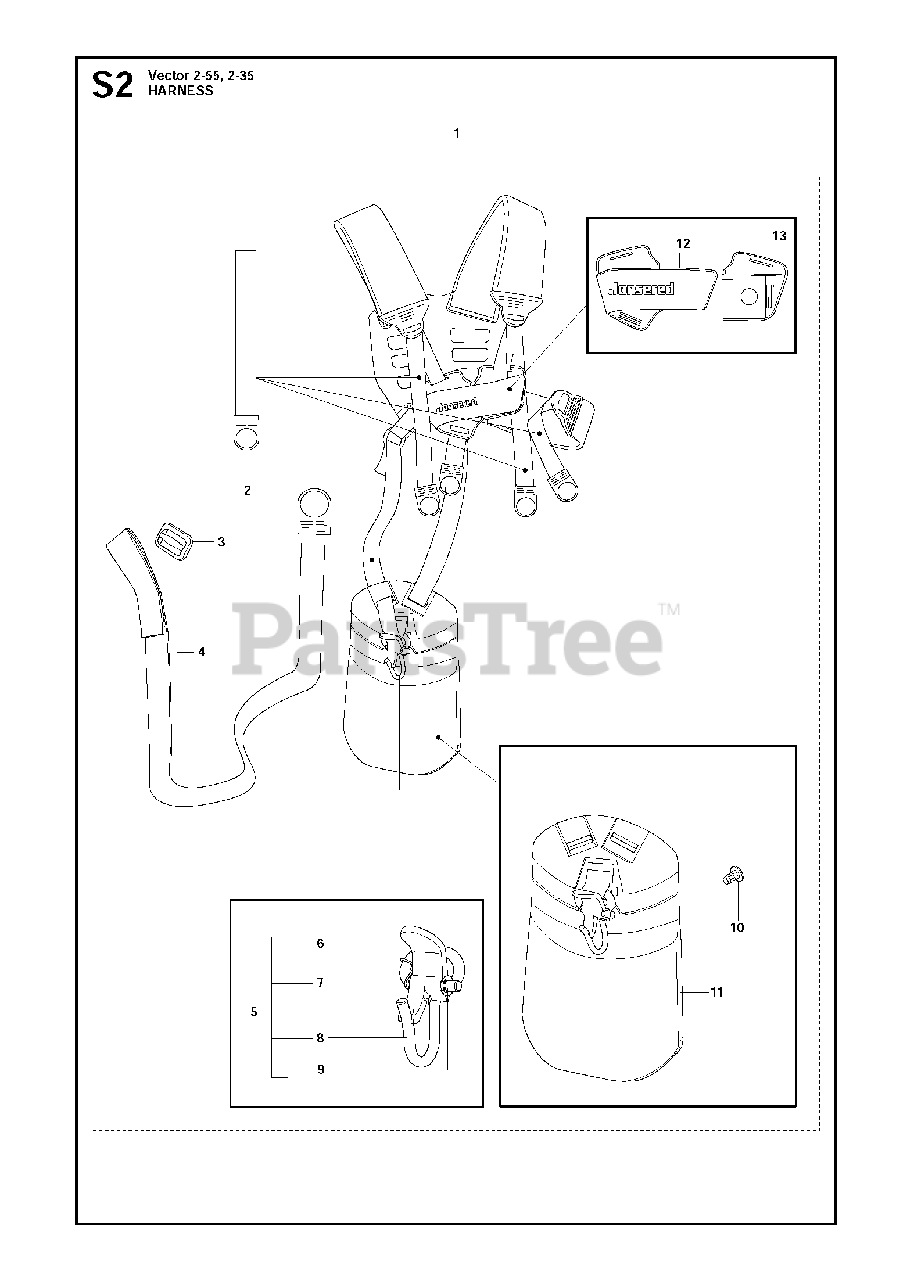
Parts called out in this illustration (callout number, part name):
1	HARNESS "VECTOR" 2-55
1	HARNESS COMPLETE
2	BAND
3	CLIP
4	BAND
5	HARNESS HOOK, COMPLETE
6	CATCH *
7	SPRING
8	HOOK
9	E-RING 5
10	RIVET
11	PROTECTOR
12	FRONT PIECE
13	FRONT PIECE
